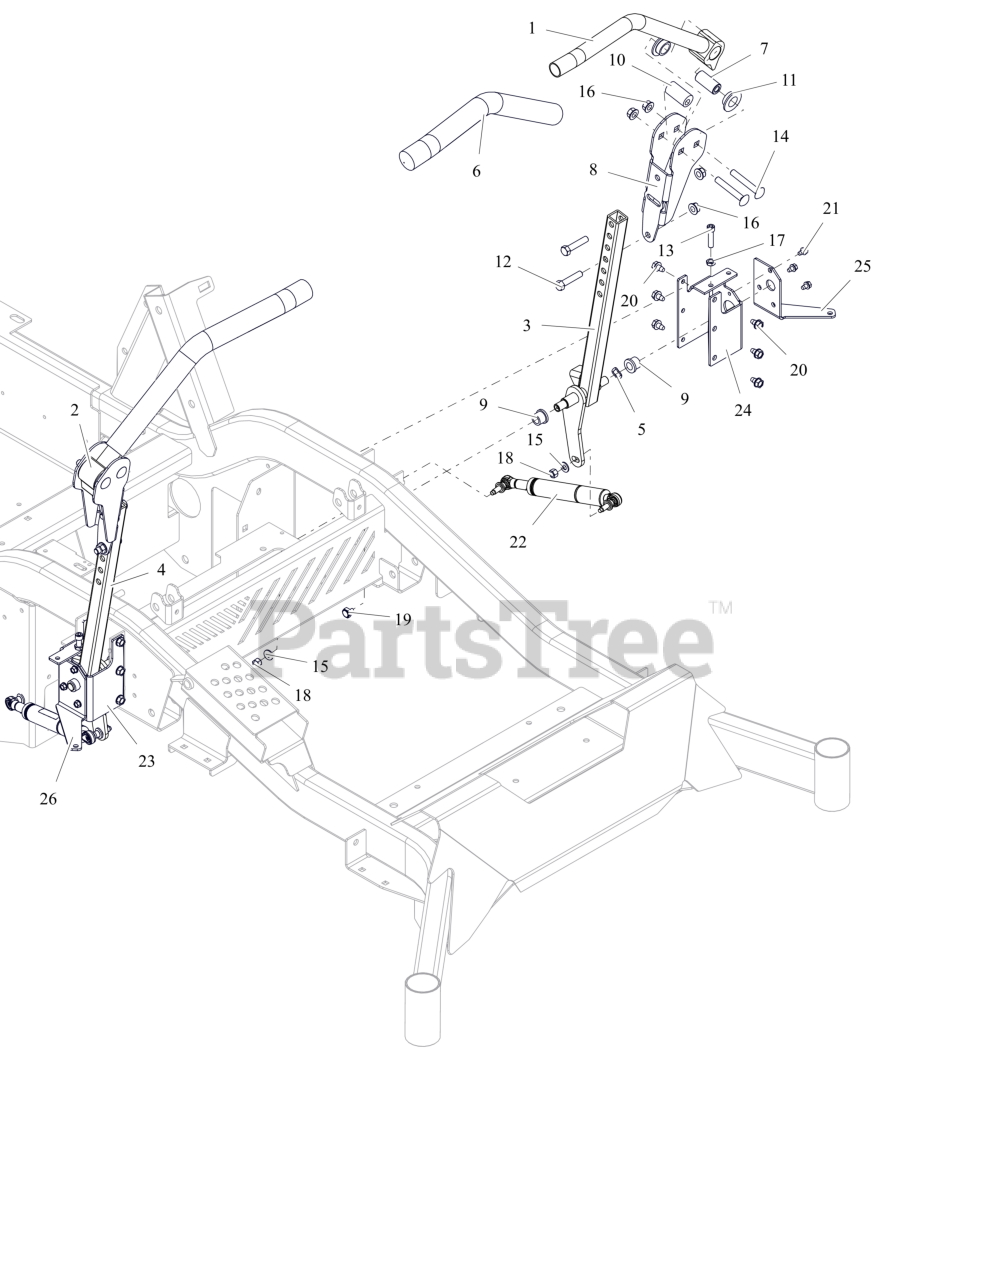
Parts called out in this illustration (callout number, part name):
1	WLDMT, CONTROL HANDLE-LH (BLACK)
2	WLDMT, CONTROL HANDLE-RH (BLACK)
3	WLDMT, STEERING -LH (BLACK)
4	WLDMT, STEERING RH (BLACK)
5	WAVE WASHER .531X.781X.125FH
6	GRIP, HANDLEBAR
7	SPACER, STEERING ARM
8	ADJ UPPER CONTROL ARM BRKT-BLK
9	BSHG, FLG .516X.750X.625X.937
10	BSHG, ECCENTRIC.406X.875X1.625
11	BSHG-FLG .762X1.48X.44 NYL
12	BLT, HEX .38-16X1.75 G5 ZCC
13	BLT, SHCS .312-18X1.25 G8 SS
14	BLT, RHSSN.38-16X2.50 G5 ZCC
15	WSHR, HRDN 0.344X0.688X0.065
16	NUT-LK-TOP-FLG .38-16 ZC120
17	NUT-JAM .312-18 G2 ZCC
18	NUT-LK-TOP-FLG M8 ZCC
19	BOLT, MAGNETIC STEERING SENSOR
20	SCR,TAP .312-18X.50 HWH TR ZCC
21	SCR,TAP .25-20X.375 HWH TR ZCC
22	DAMPER, NEUTRALIZING
23	WLDMT, STEERING MOUNTING- RH (ORANGE)
24	BRKT, STEERING MOUNTING -LH (ORANGE)
25	BRKT, FRONT FENDER MOUNT-LH (BLACK)
26	BRKT, FRONT FENDER MOUNT-RH (BLACK)
